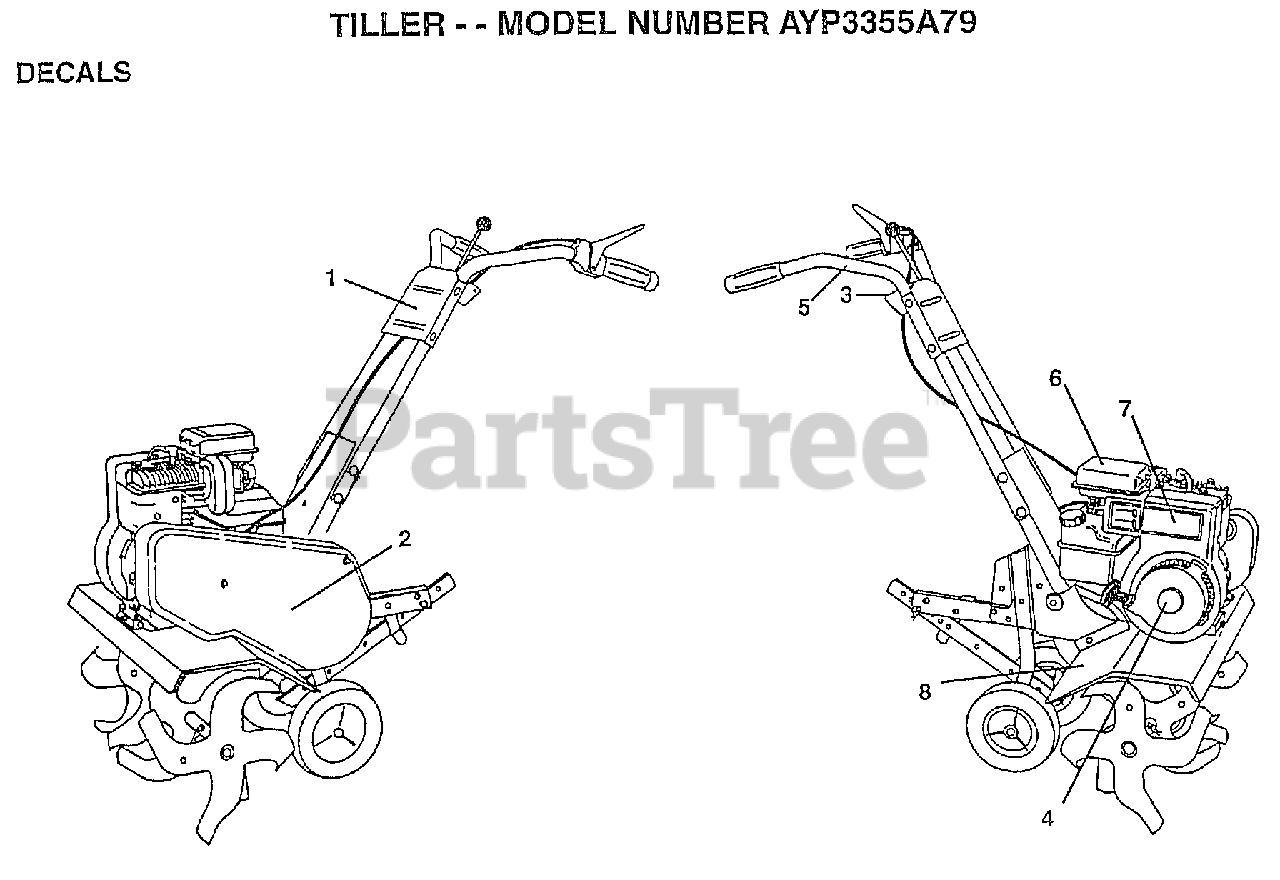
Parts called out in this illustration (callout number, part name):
1	DECAL.CNTRL.PNL.5
2	DECAL.BELT.GUARD
3	DECAL REVERSE
4	DECAL, 5 HP
5	DECAL TI
7	DECAL, BRIGGS & STRATTON
8	DECAL TI
